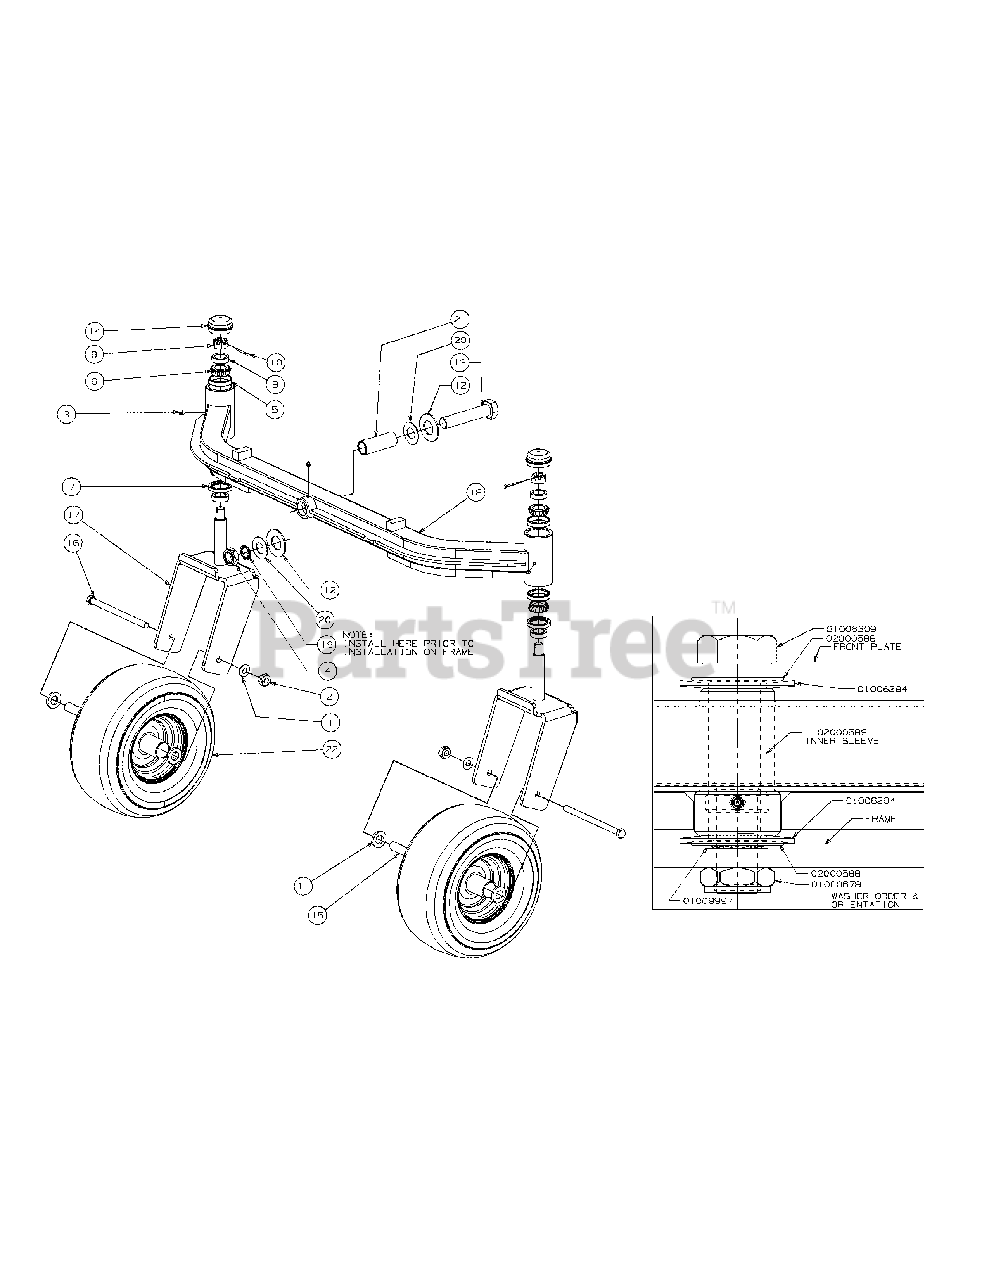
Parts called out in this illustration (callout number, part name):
1	Washer, 1/2 x 1 Shim
2	Nut, 1/2-20, Center Lock
3	Grease Fitting
4	Nut, Jam, 1.0-14, Insert Lock
5	Cup Bearing
6	Bearing Cone
7	Seal
8	Ring Seal
9	Slotted Nut, 3/4-16
10	Cotter Pin, 5/32, 1.25
11	Spacer, .812 ID x .218LG
12	Bell Washer, 1.25 ID x 2.5 OD x .180
13	Hex Cap Screw, 1-14 x 5.0
14	Grease Cap, 1.986 OD
15	Wheel Spacer
16	HHCS, 1/2-20, 7.50
17	Yoke, Caster Wheel
18	Front Axle Assembly
19	Retainer Extension, Self Locking
20	Flat Washer, 1.00 ID x 2.00 OD x .075
21	Spacer, 1.005 ID x 1.25 OD x 3.6
22	Wheel, 13 x 6.50 x 6.0, Beige, includes
